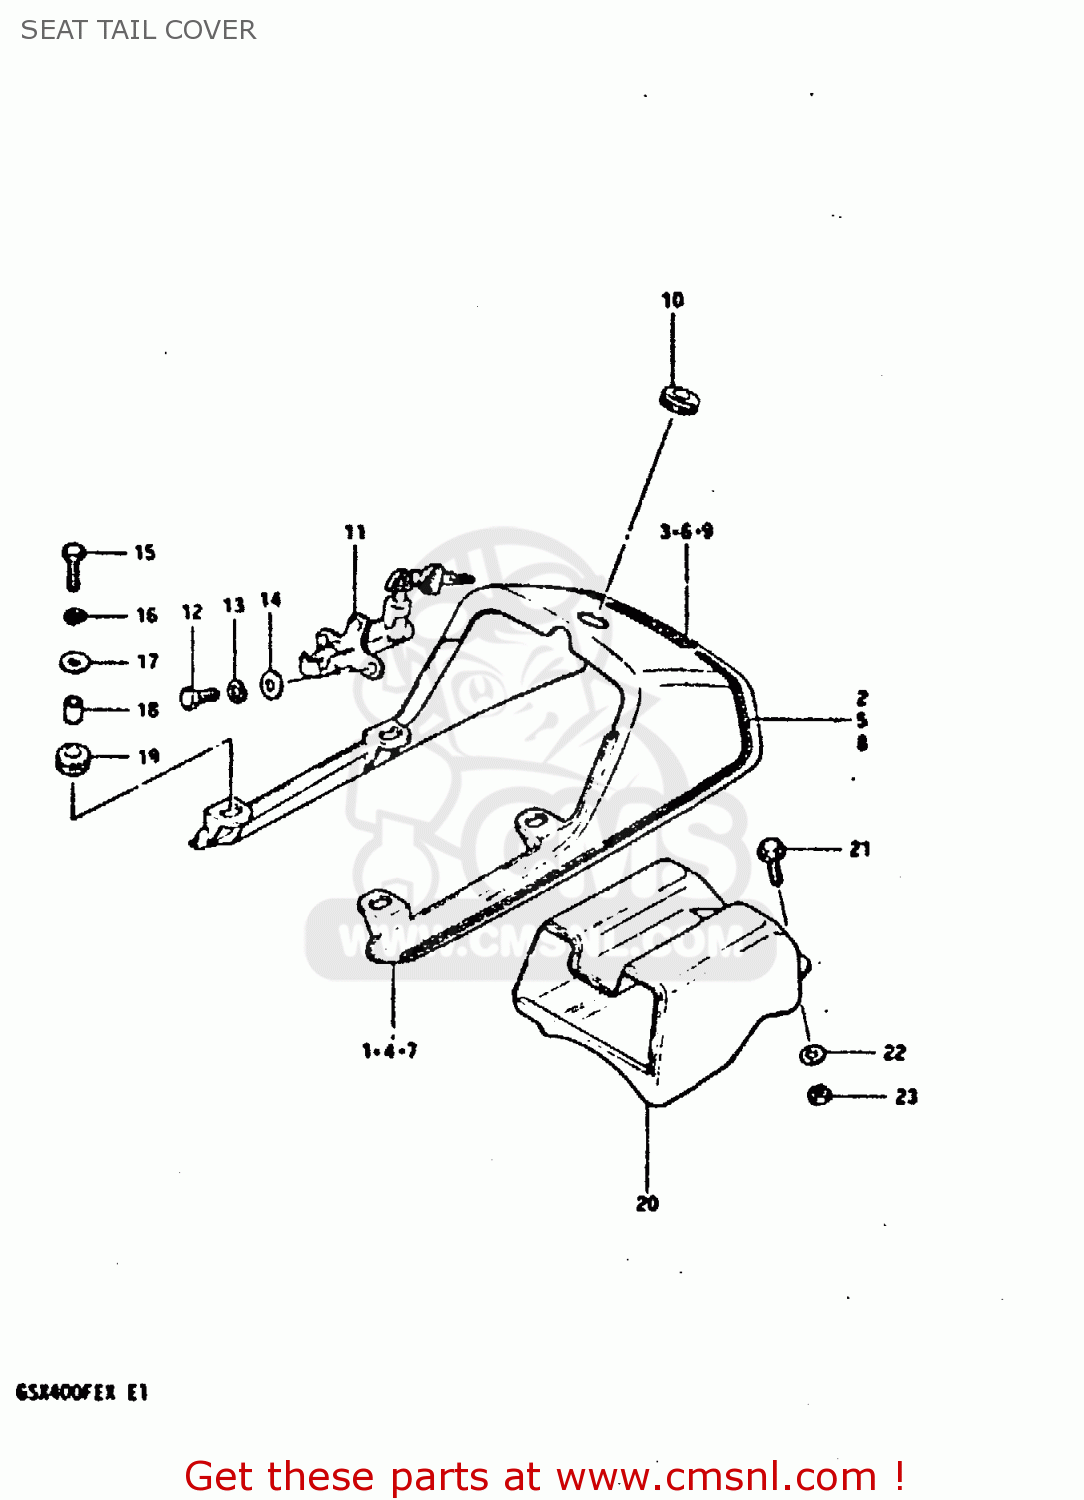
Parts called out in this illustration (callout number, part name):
1	COVER,SEAT TAI
2	TAPE SET
3	EMBLEM,SEAT TAIL(SILVER)
4	COVER, SEAT TAIL (SILVER)
5	TAPE SET
6	EMBLEM (RED)
7	COVER, SEAT TAIL (RED)
8	TAPE SET
9	EMBLEM,SEAT TAIL(SILVER)
10	GROMMET,SEAT LOCK HOLE
11	LOCK SET,SEAT
12	BOLT
13	LOCK WASHER
14	WASHER
15	BOLT
16	LOCK WASHER
17	WASHER(6,5X22X1.6)
18	SPACER(6.5X10.5X12)
19	CUSHION
20	BOX, SEAT TAIL
21	BOLT
22	WASHER
23	NUT
